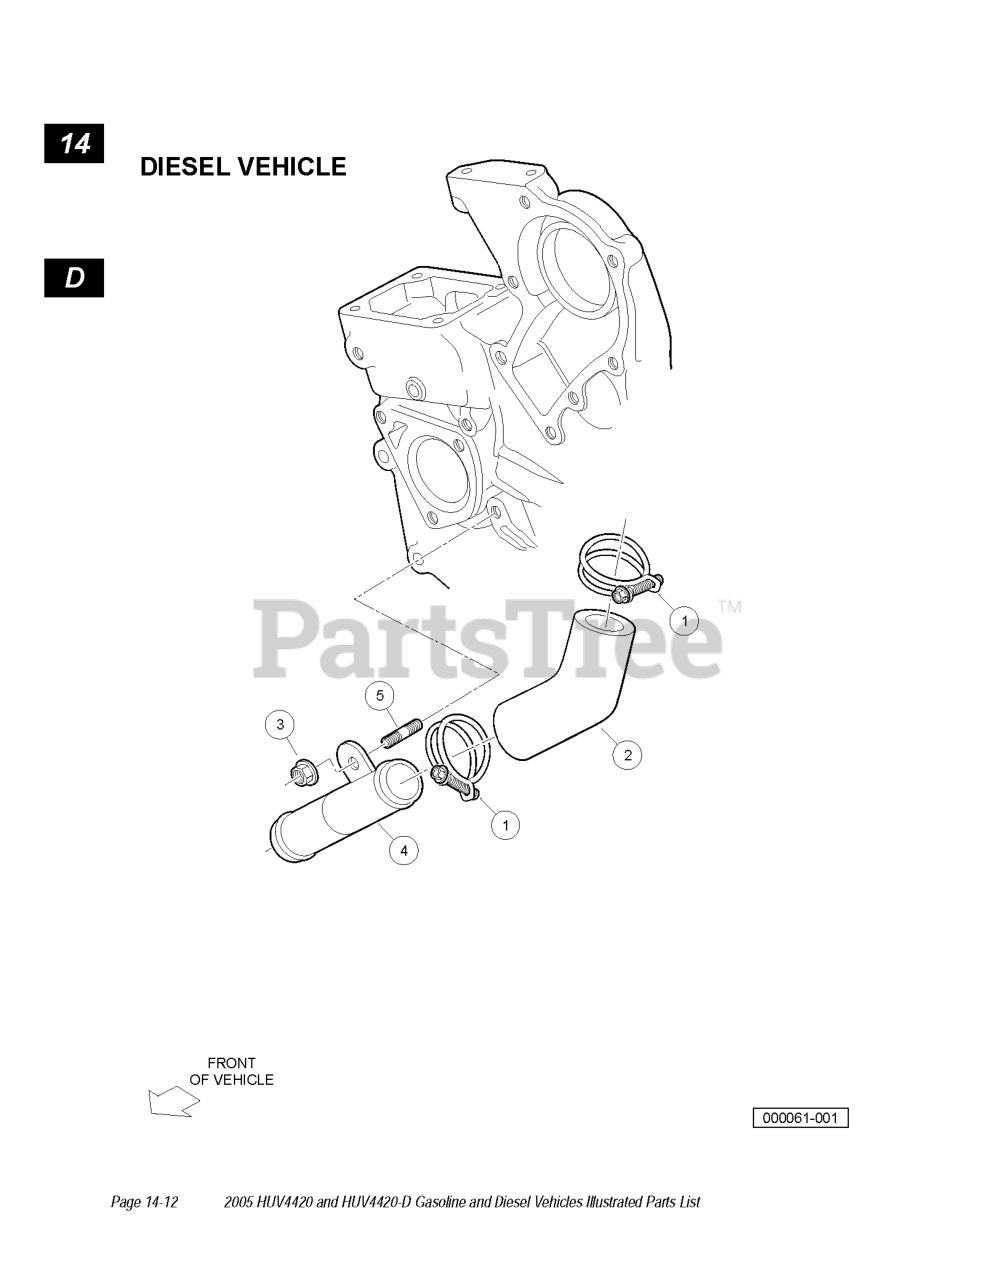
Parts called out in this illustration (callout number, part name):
1	BAND, PIPE, WITH NUT
2	PIPE, WATER, BENT
3	NUT, FLANGE, M6
4	PIPE, WATER, BENT
5	STUD, M6X15
